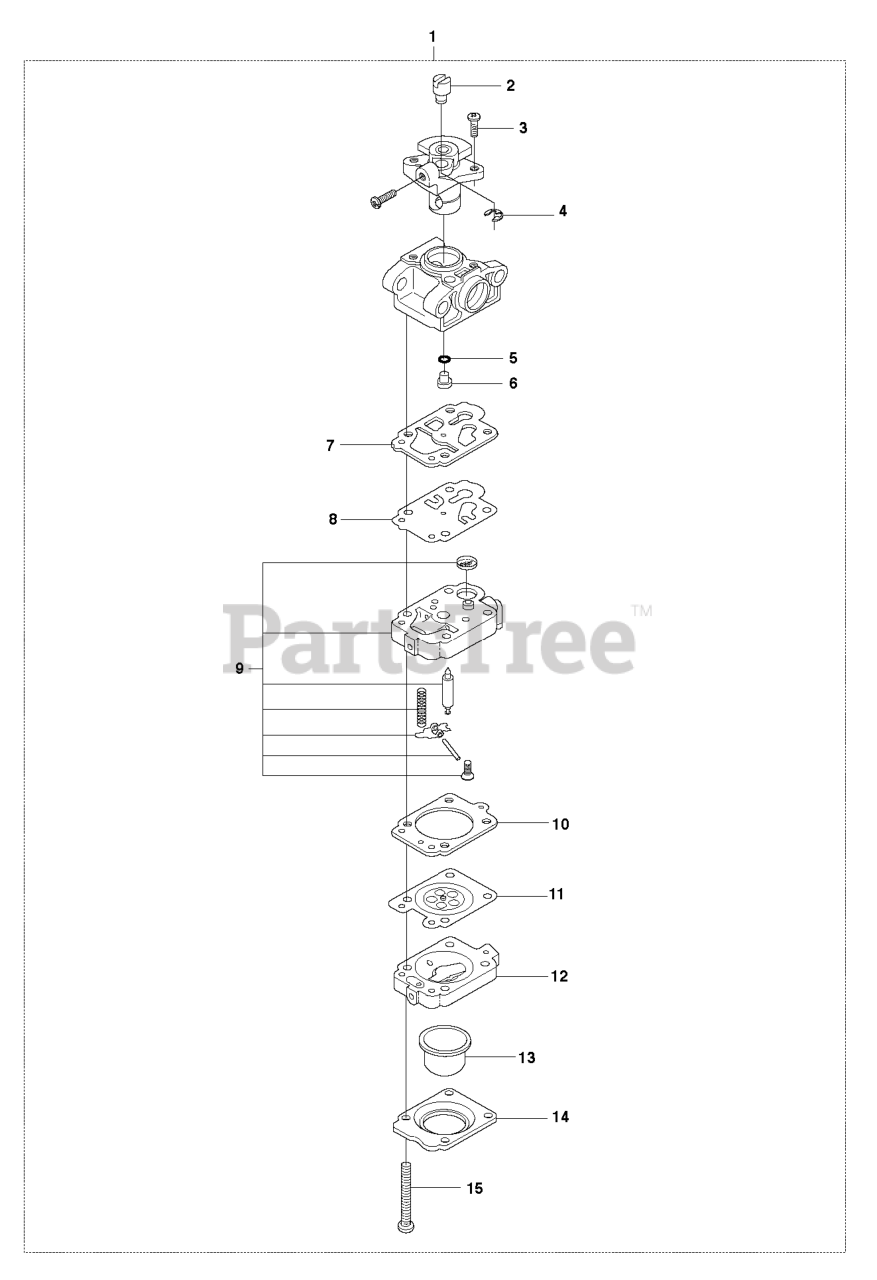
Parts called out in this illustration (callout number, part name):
1	CARBURETOR
2	CONNECTION
3	SCREW
4	RETAINING RING
7	GASKET
8	%GASKET
14	PUMP COVER
